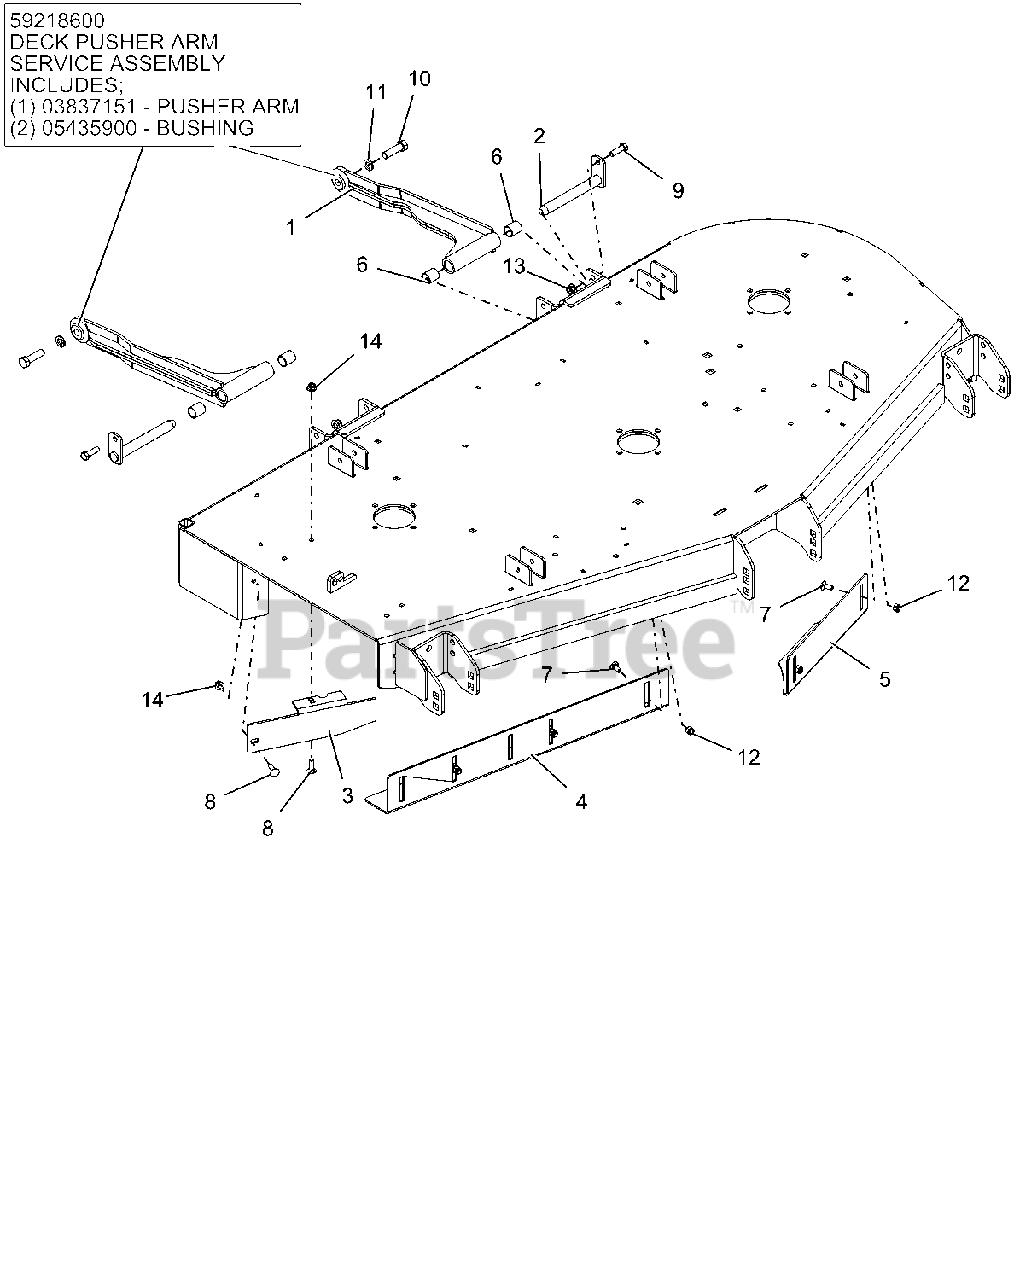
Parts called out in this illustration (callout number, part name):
1	DECK PUSHER ARM SERVICE ASSEMBLY
1	PUSHER ARM
1	BUSHING
1	WLDMT, DECK STABILIZER ARM
2	WLDMT, MOWER MTG. PIN
3	BAFFLE, 60" DISCHARGE
4	BAFFLE, 60" RH VACUUM
5	BAFFLE, 60" LH VACUUM
6	BRG, .750 X .875 X 1.000
7	BLT-RDHDSQNK .31-18X.75 G5 YWZC
8	BLT-RDHDSQSHNK .31-18X1.00 G5 Y
9	BLT-HEX .38-16X1.25 GR5 YWZC
10	BLT-HEX .50-13X1.75 GR5 YWZC EP80
11	WSHR-LK .50X.125 REG YWZC
12	NUT-LK-NYL .312-18 YWZC
13	NUT-LK-NYL-FLG .38-16 YWZC
14	NUT-LK-NYL-FLG .31-18 YWZC
